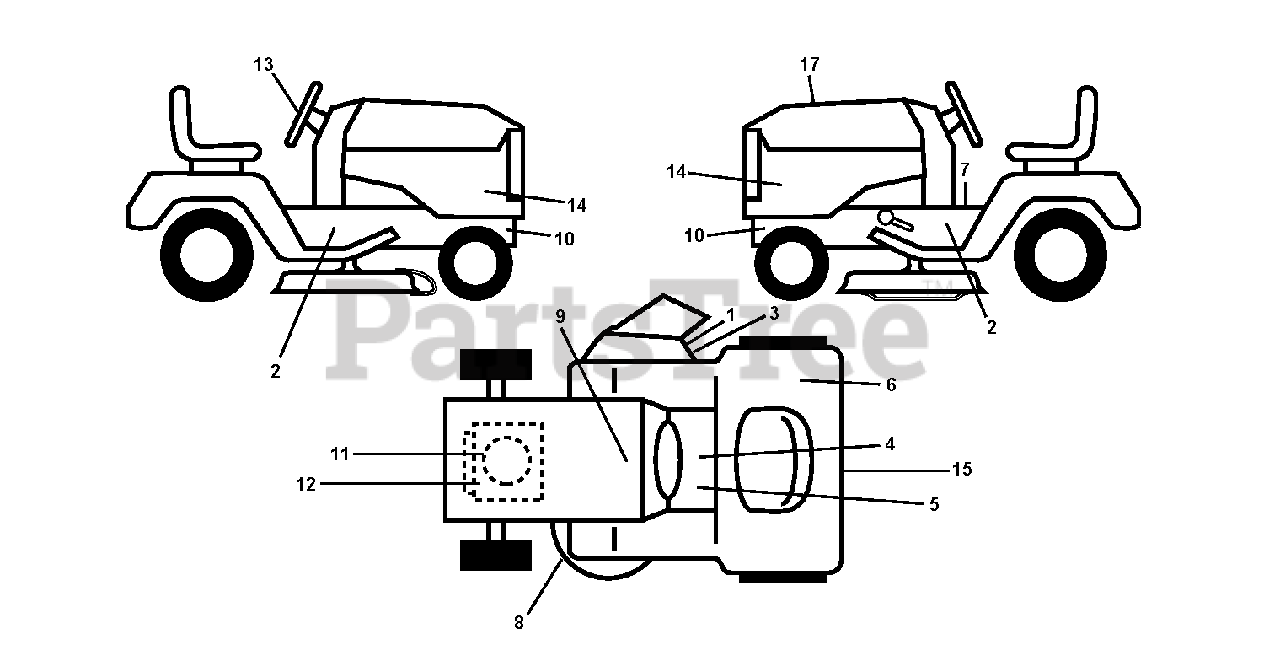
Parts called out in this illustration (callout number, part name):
1	DECAL.INTERNATIONL.CUTFINGER
3	DECAL, DEFLECT WARNING
4	DECAL PARK BRAKE
8	DECAL V BELT SCHEMATIC
9	DECAL BTRY SYMBOLS
